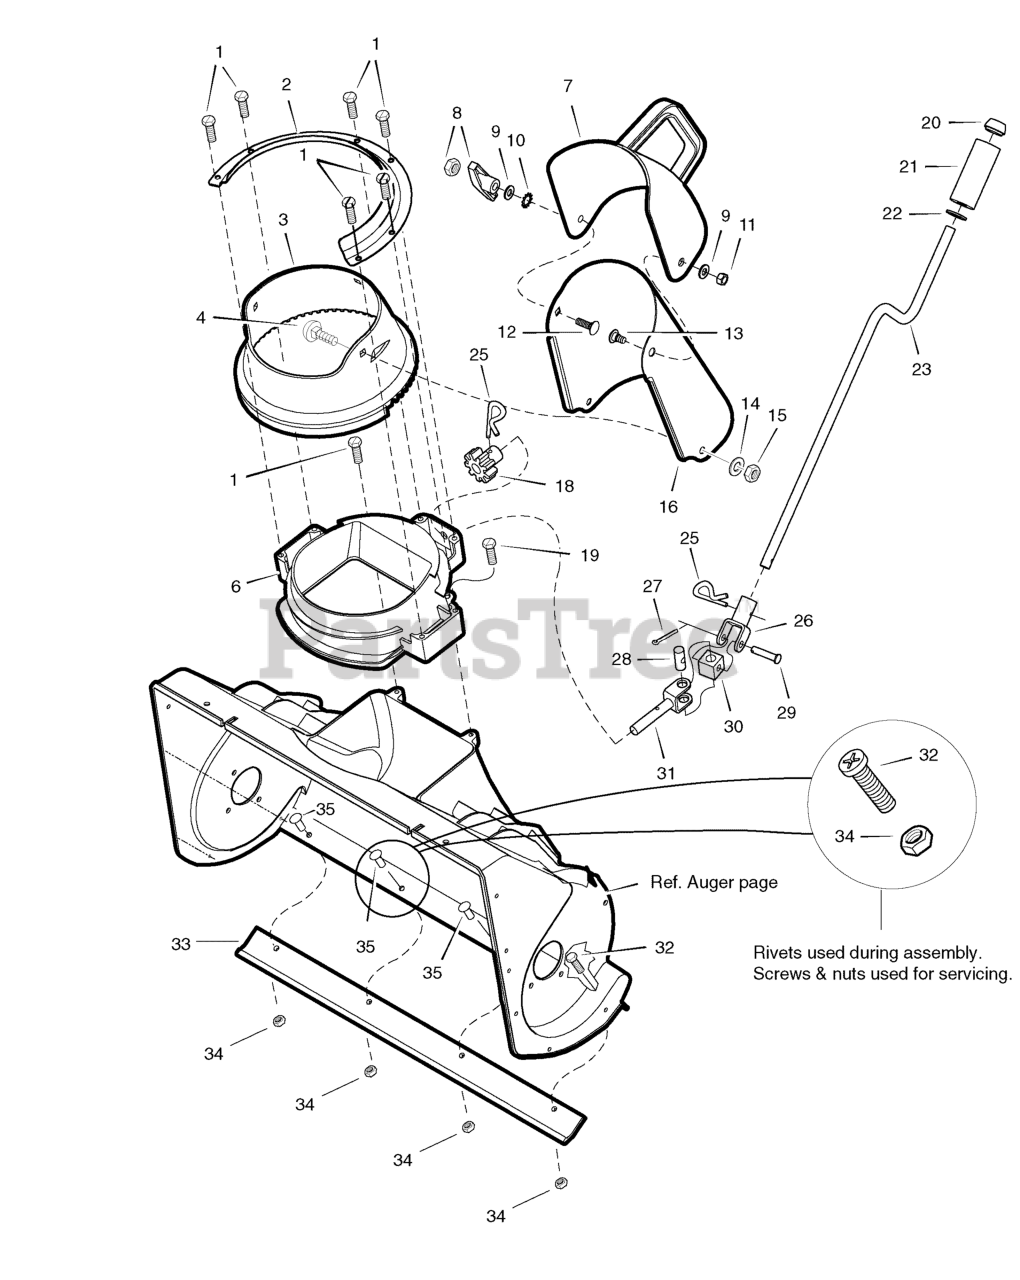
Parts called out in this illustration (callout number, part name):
1	Screw 1/4-14
2	Retainer, Chute Ring
3	Ring, Chute
4	Bolt, Carr 5/16-18x.75
6	Neck, Chute
7	Chute, 22" Upper
9	Washer
10	Lockwasher
11	Locknut 5/16-18
12	Bolt, Carr 5/16-18
13	Bolt, Upper Chute
14	WASHER, Flat, 13/32
15	Nut
16	Chute, Lower
18	Gear, 9-Tooth
19	Screw, 1/4-14 x .75
20	Nut, Push
21	Knob, Sleeve
22	WASHER, Flat, 13/32
23	Crank, Chute
25	Pin, Hair
26	Yoke Assy, Adapter
27	Pin, Cotter
28	Pin, Universal Joint
29	Pin, Clevis
30	Housing, Universal
31	Rod, Lower Crank
32	Screw 1/4-20 x .75
33	Blade, Scraper
34	Locknut, Hex 1/4-20
